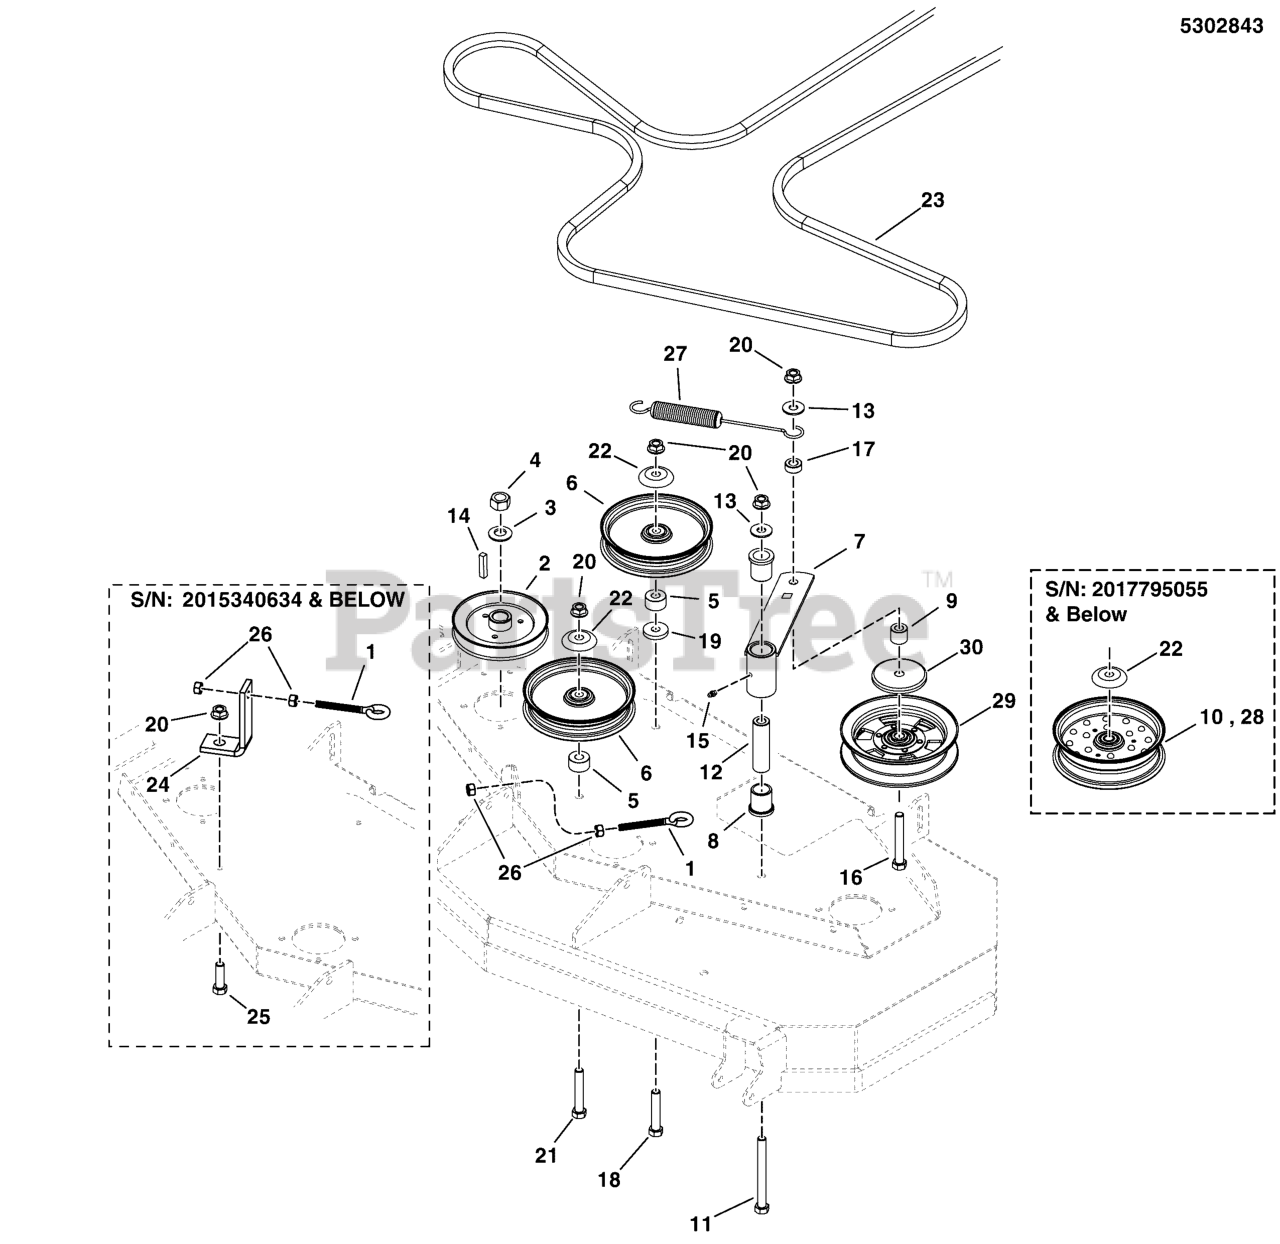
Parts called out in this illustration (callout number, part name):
1	EYEBOLT, 3/8-16 X 4, 2.13THRD, .75EYE, C
2	PULLEY, 5.540OB X .985ID, SINGLE B-SEC
3	WASHER, 3/4 BELLEVILLE CL/ZC
4	NUT, 3/4-16 Hex
5	SPACER, .52 X 1.25 X .70, PM, CZ
7	ASSM, IDLER ARM
8	BUSHING, FLANGE
9	SPACER, .52 X 1.00 X .88, PM, CZ
10	PULLEY, IDLER, 6.75 OD X 1.62 FACE
11	BOLT, 1/2-13 X 5" GD5 YZ
12	SPACER, .52 x 1.00 x 3.50
13	WASHER, 1/2" USSZ
14	KEY, 1/4" SQ. X 1-1/4
15	GREASE FITTING, 1/4-28 Straight
16	BOLT, 1/2-13 X 3-1/2, HEX HD, GD5, CZ (SV)
17	SPACER, .52 X 1.00 X .44, CZ
18	BOLT, 1/2-13 X 2-3/4 GD5 CZ
19	WASHER, .53 X 1.50 X .25
20	NUT, Hex Flange, Nylock, 1/2-13
21	BOLT, 1/2-13 X 2-1/2" GD5 CZ
22	SHIELD, PULLEY BEARING, CZ
23	BELT, BP-SEC, 146.00EL, LG ARAMID, WRPD
24	BRACKET, EYEBOLT MOUNT - BLK
25	BOLT, 1/2-13 X 1-1/2 GD5 CZ
26	NUT, 5/16-18 HEX
27	SPRING-EXT, 1.04 ODX10.535LGX.148WR, BLK
28	PULLEY, DP V-IDLER,6.25OD
29	PULLEY,IDLER,BACKSIDE,NOSEAM 6.25ODX.5ID
30	SHIELD, BEARING, 1/2 ID X 2-7/8 OD, CZ
